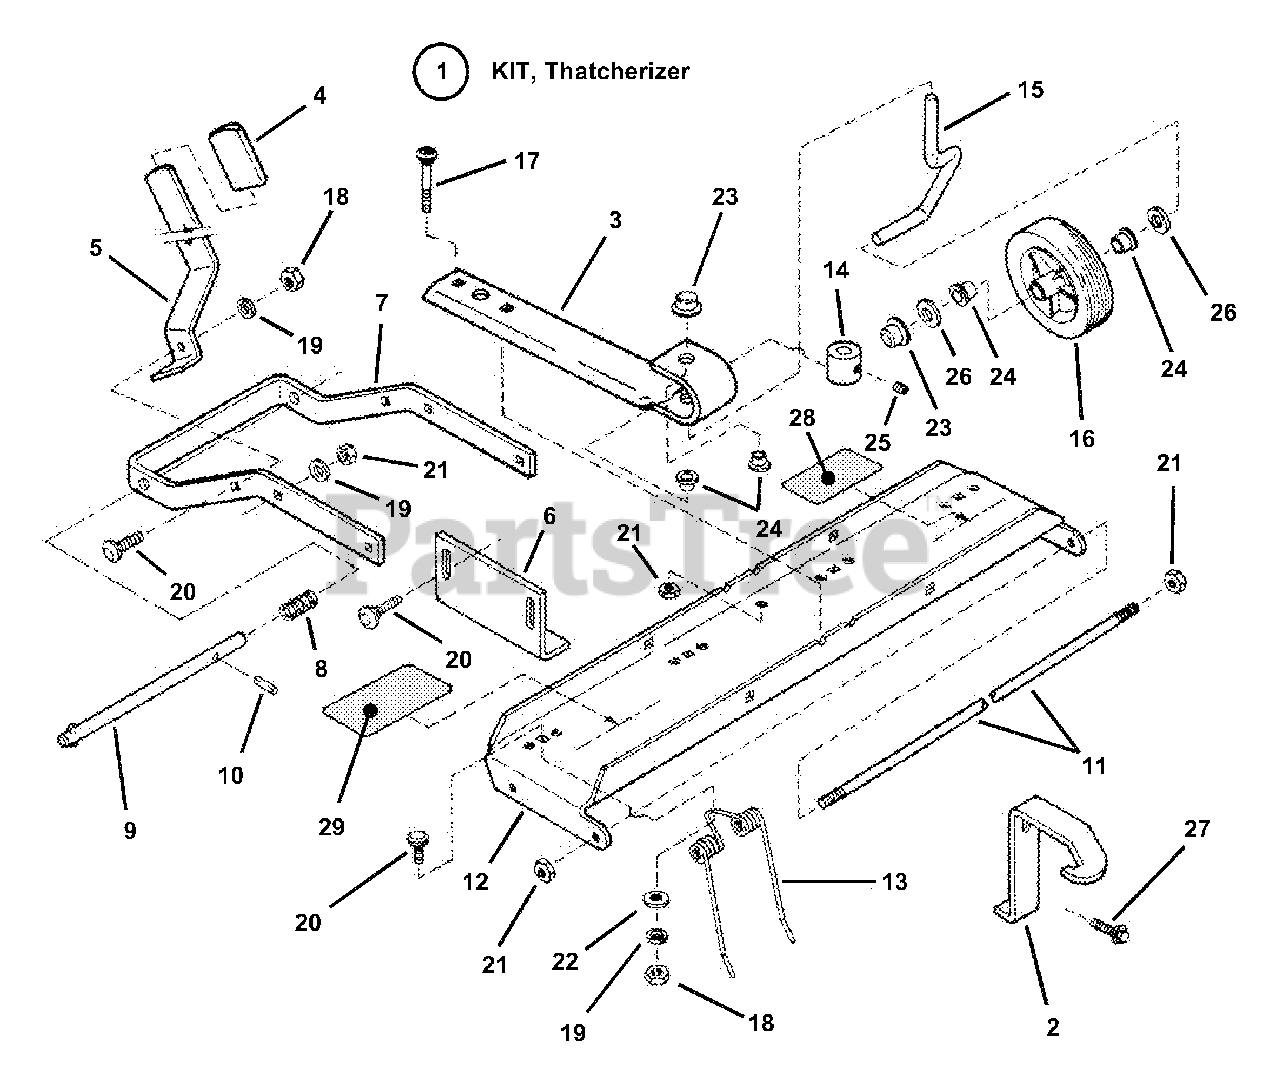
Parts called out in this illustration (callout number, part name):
1	KIT, 25" & 33" Thatcherizer
2	BRACKET, Transport Lock
3	SUPPORT, Wheel Assembly
4	GRIP, Handle
5	HANDLE, Lift
6	BRACKET, Frame Mount
7	FRAME, Thatcherizer
8	SPRING, Coupler
9	ROD, Mounting
10	PIN, 1/4 x 1-3/4" Roll
11	ROD, Tine Retainer
12	TRAY, Tine (30.5")
13	SPRING, Tine Thatching
14	BUSHING
15	AXLE, Wheel
16	WHEEL, 7"
17	BOLT, 1/4-20 x 1-3/4" Carr.
18	NUT, 5/16-18 Hex
19	WASHER, 5/16 Split Lock
20	BOLT, 5/16-18 x 1" Carriage
21	NUT, 1/4-20 Hex Lock
22	WASHER, Reinforcing
23	NUT, 1/2 Push
24	BEARING, Nyliner (Snap-In)
25	SCREW, 5/16-18 x 1/4" Slot Set
26	WASHER, 1/2 Flat
27	SCREW, 5/16-18 x 3/4" Self-Tap
28	DECAL, Instruction
29	DECAL, Thatcherizer
